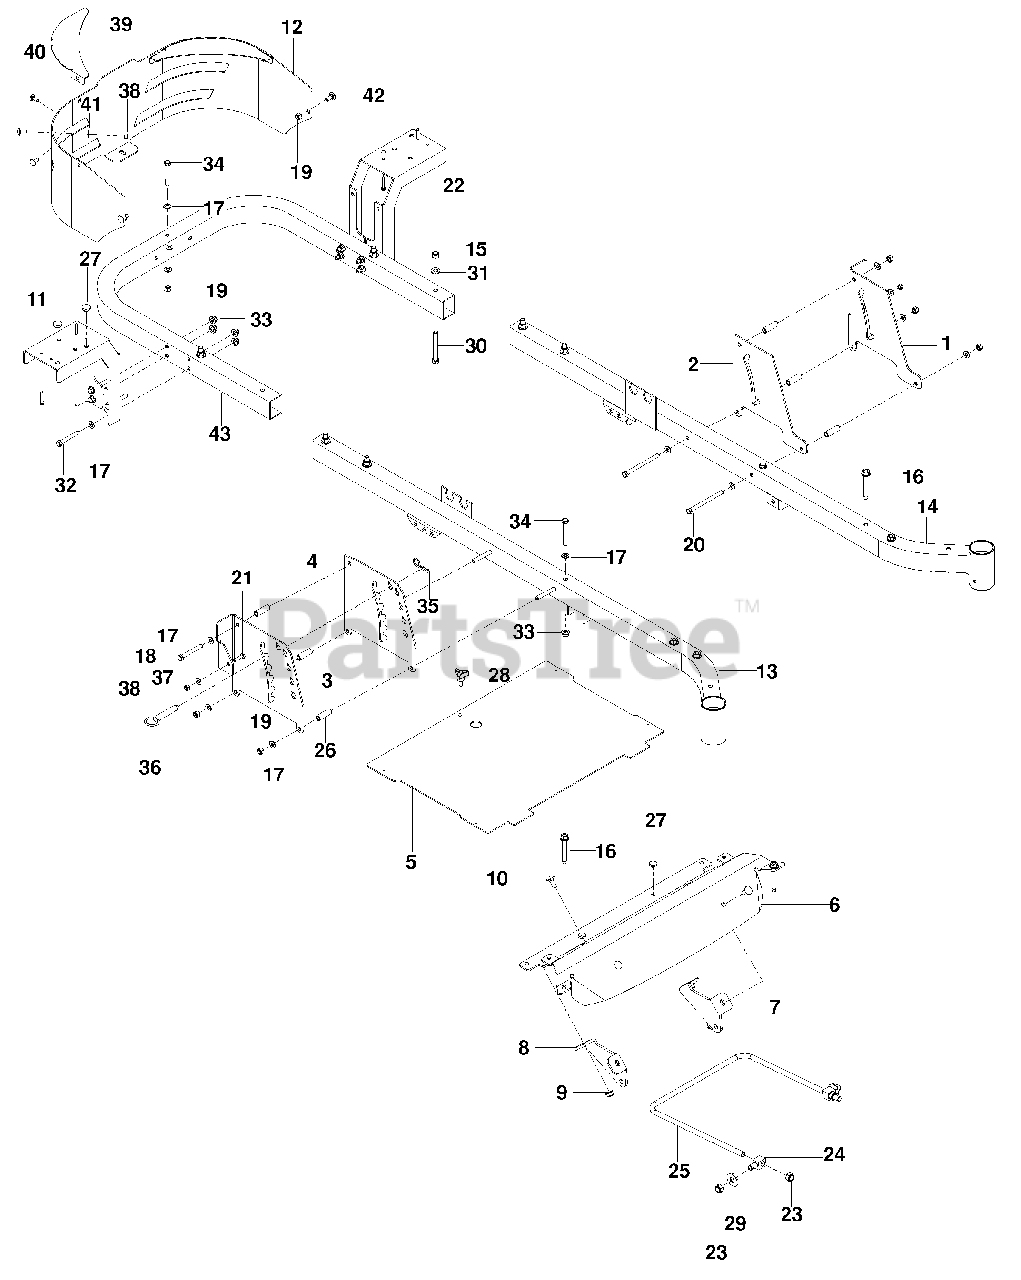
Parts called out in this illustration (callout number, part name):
1	Plate, Outer Brake Blk
2	Plate, Brake Latch Blk
3	Plate, Deck Height Blk
4	Plate, Deck Height Blk
5	Foot Plate W/Decals
6	Foot Rest Org
7	Mount, Strut, Rt, Blk
8	Mount, Strut, Lt, Blk
9	Nut 3/8-16 Hex Flg Nyloc
10	Rhsnb 3/8-16 X 1
11	Support, Fender
12	Guard, Wide Engine Org
13	Frame, Front Rt Org
14	Frame, Front Lt Org
15	Nut 3/8-16 Hex Nyloc
16	Bolt 3/8-16 X 25/8 Thd Frm
17	Washer 5/16 Sae Flt
18	Hcs 5/16-18 X 2 1/2
19	Nut 5/16-18 Hex Nyloc
20	Hcs 5/16-18 X 4
21	Hcs 1/4-20 X 1
22	Screw 10-12 X 1 1/4 Wsh Hd
23	Nut 7/16-14 Hex Nyloc
25	Link, Front Suspension
26	Spacer 1/2 Od X 1 1/2
27	Grommet, Bumper
28	Knob W/Stud
29	Washer 1/2 Flt
30	Hcs 3/8-16 X 3
31	Washer 3/8 Sae Flt
32	Hcs 5/16-18 X 2 1/4
33	Nut 5/16-18 Flange Nyloc
34	Hcs 5/16-18 X 2 3/4
35	#4 Hairpin
37	Washer 1/4 Flt Sae
38	Nut 1/4-20 Hex Nyloc
39	Support, Corner Org
40	Rhssnb 1/4-20 X 5/8
41	Washer 1/4 Flat Zd
42	Rhsnb 5/16-18 X 3/4
43	Frame, Rear Org
